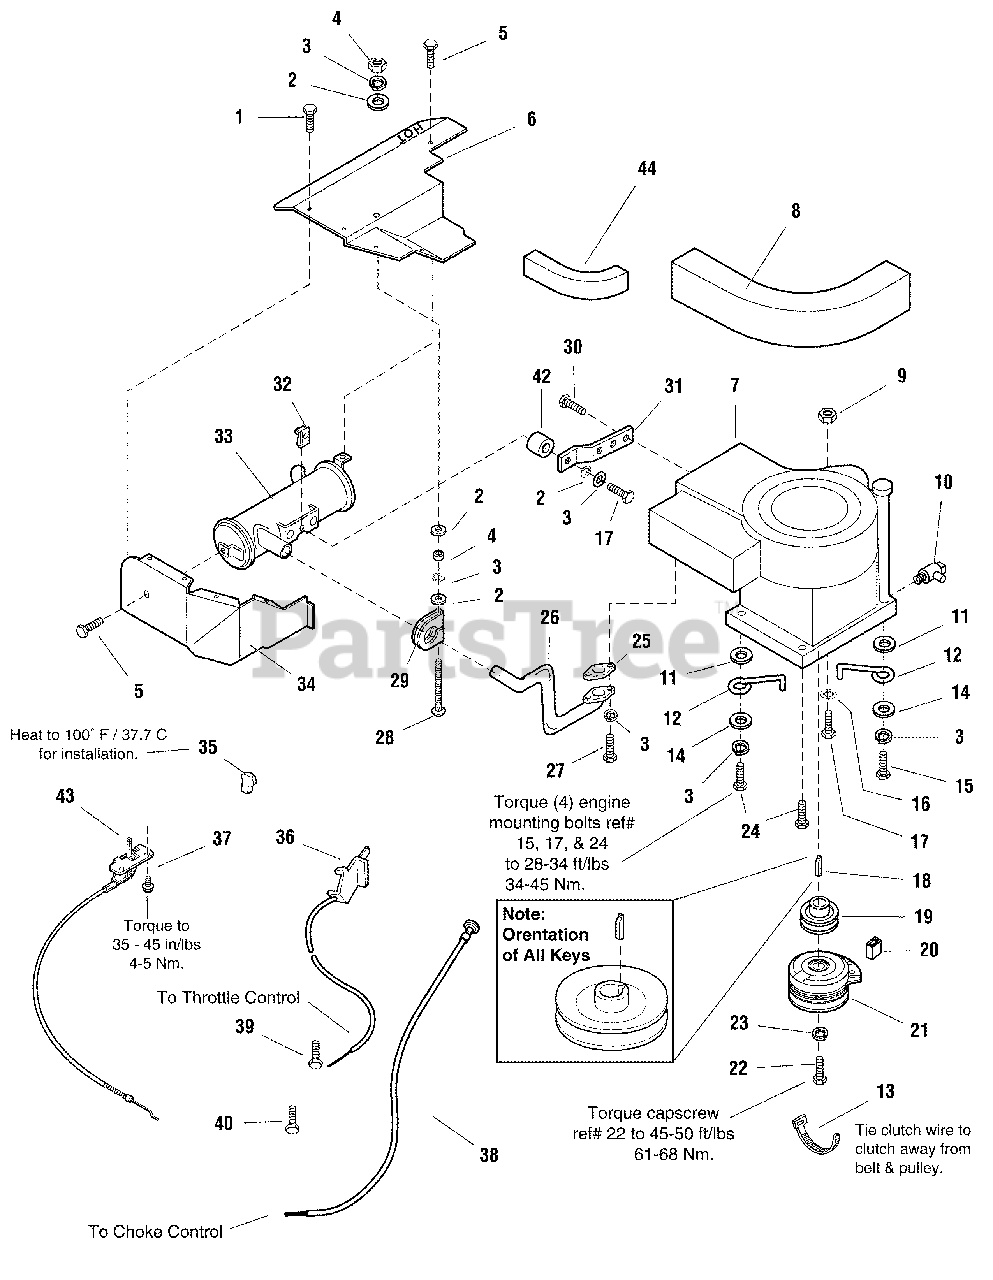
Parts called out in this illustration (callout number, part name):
1	CAPSCREW, Self-Tapping, #10-16 x 1/2
2	WASHER, 5/16
3	LOCKWASHER, 5/16
4	NUT, Hex, 5/16-18
5	CAPSCREW, Hex Head, Taptite, 5/16-18 x 1/2
6	DUCT, R.H., Top
8	SEAL, Air Inlet
9	NUT, Flange, Whizlock, 5/16-18
10	VALVE, Shut-Off
11	WASHER, Plain
12	BELT STOP
13	TIE, Self Locking
14	WASHER, 3/8
15	CAPSCREW, Taptite, 3/8-16 x 2
16	PUSH NUT, 5/16-18
17	CAPSCREW, Hex, Whizlock, Flange, 5/16-18 x 1-1/2
18	** KEY
19	PULLEY, Engine
20	SLEEVE, Clutch Anchor
21	CLUTCH, Electric, Kit
22	CAPSCREW, Hex Head, 7/16-20 x 2-1/2
23	LOCKWASHER, 7/16
24	CAPSCREW, Taptite, 3/8-16 x 1-1/2
25	GASKET, Muffler
26	PIPE, Exhaust
27	CAPSCREW, Socket Head, 5/16-18 x 3/4
28	CARRIAGE BOLT, 5/16-18 x 3-1/4
29	CLAMP, Muffler
30	CAPSCREW, Hex Head, 1/4-20 x 7/8
31	SUPPORT, Muffler
32	NUT, Speed, Lug Type, 5/16-18
33	MUFFLER ASSEMBLY
34	DUCT, L.H.
35	KNOB, Throttle
36	THROTTLE CONTROL ASSEMBLY
37	SCREW, Plastite, 1/4-10 x 1/2
38	CABLE, Choke Control
39	SCREW, Hex, Washer Head, B&S #94909
40	SCREW, Thread Forming W/Washer, B&S #95220
41	STOP, Throttle (Not Pictured, Export Models Only)
42	SPACER
43	THROTTLE CONTROL ASSEMBLY
44	SEAL, Edging
